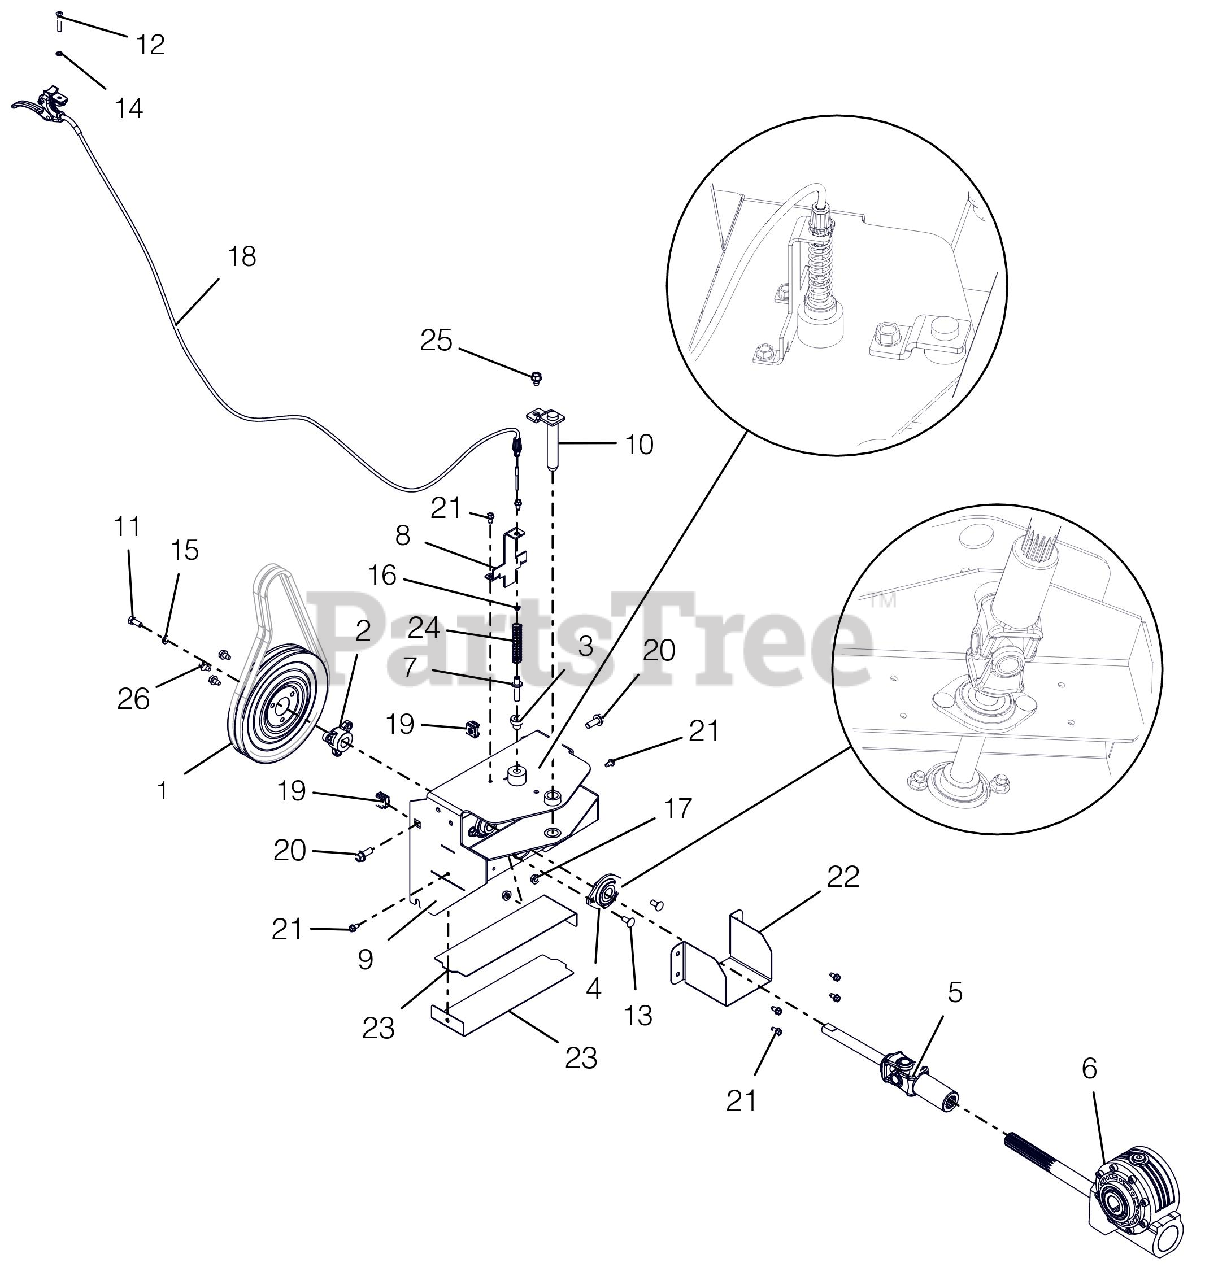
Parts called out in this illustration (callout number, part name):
1	PULLEY, SPIN FORM DUAL GROOVE
2	PULLEY HUB, BOLT-ON D-BORE .75
3	SPACER -FLANGED .390X.500X.781
4	BEARING, 2 BOLT FLANGE -.75 ID
5	DRIVELINE, SERIES 07 (U-JOINT)
6	GEARBOX, WORM - 8.25:1
7	PIN, ADJUSTABLE ANGLE BRUSH
8	BRKT, PIN HOLDER
9	ADAPTER, BRUSH
10	WLDMT, BRUSH PIN
11	BLT-HEX .31-24X.75 YWZC GR5
12	SCR-MCH .25-20X1.50 OVAL HD
13	@BLT-RDHDSQNK .31-18X.75 G5YZ
14	WSHR-LK-INT .250 TH TYA
15	WSHR-LK .312X.097 HVY YWZC
16	@NUT-HEX 10-24 YWZC
17	@NUT-LK-TOP-FLG .31-18 YWZC
18	CABLE, REMOTE BRUSH LOCK
19	NUT-RETNR .38-16 TINRMAN
20	BLT-SERHFWH .375-16X1.0 YWZC
21	SCR-TAP .25-20X.50 HWH TR YWZ
22	GUARD, BRUSH U-JOINT
23	GUARD, BRUSH PTO
24	SPRING, COMPRESSION
25	@SCR-TAP .38-16X.50 HWH TR YWZ
26	@SCR-TAP .31-18X.50 HWH TR YWZ
